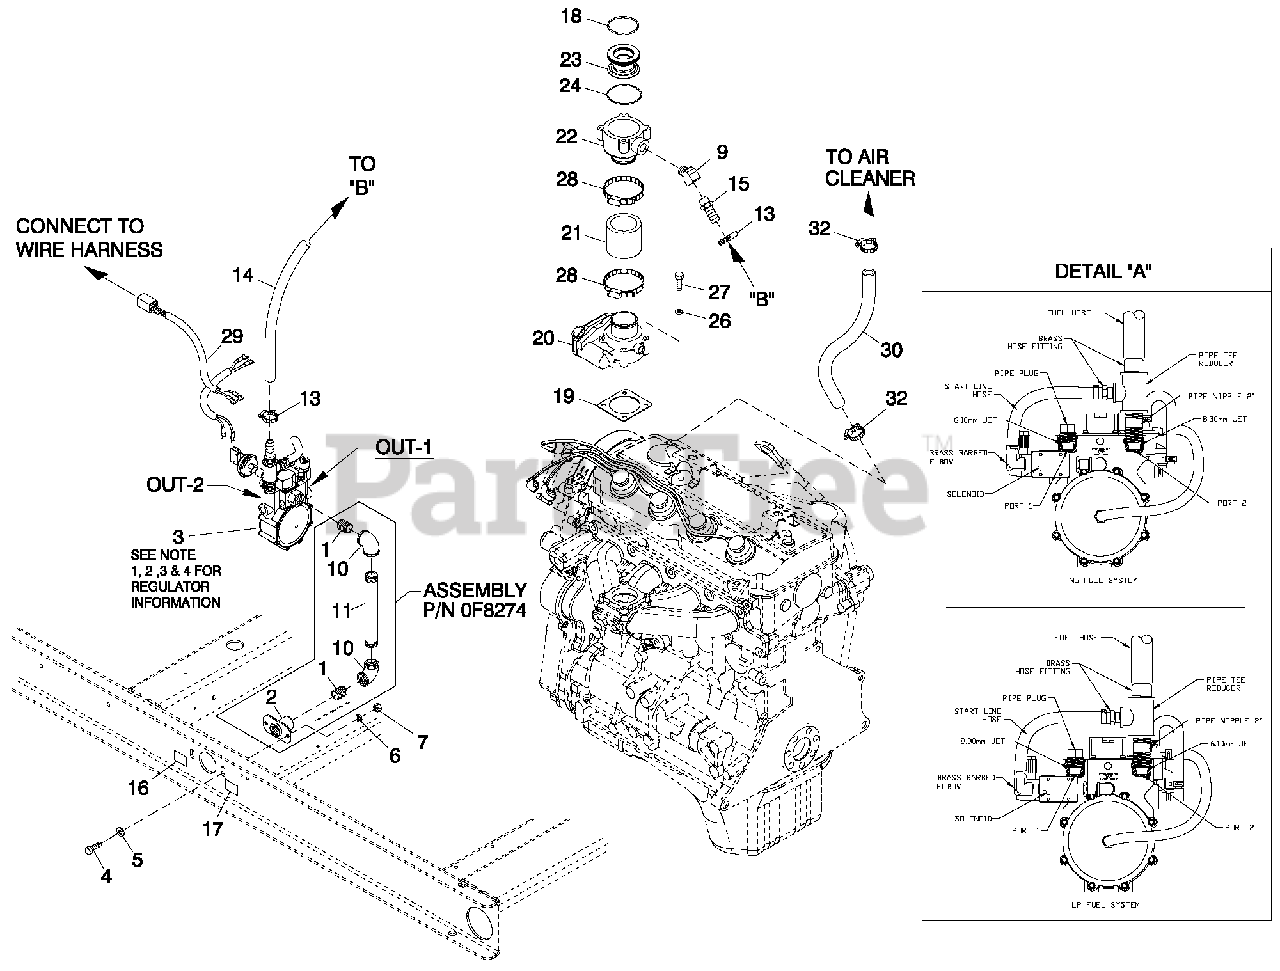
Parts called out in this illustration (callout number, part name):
1	NIPPLE CLOSE 3/4X1.375
2	FLANGE FUEL INLET
3	REGULATOR ASSY 2.4L (25KW)
4	SCREW HHC M8-1.25X 20 G8.8
5	WASHER FLAT 5/16-M8 ZINC
6	WASHER LOCK M8-5/16
7	NUT HEX M8-1.25 G8 CLEAR ZINC
9	STREET EL 45D1/2 NPT BRASS
10	ELBOW 90D 3/4 NPT
11	NIPPLE PIPE 3/4lNPTlX7
13	CLAMP HOSE #10.56-1.06
14	HOSE 3/4 ID LPG & NG (18" LG)
15	BARBED STR 1/2 NPT X 3/4
16	DECALlINLETlPRESSUREl
17	DECALlFUELlNLETlNGl(NATURALlGASlAPPLICATION)
18	O-RINGl45.63 DlX2.62 WIDTH
19	GASKET BOSCH 32
20	ACTUATOR BOSCH 40 GOVERNOR (45KW)
21	HOSE COOL 2 IN ID 20R4 (45KW)
22	MIXERACTUATOR 32MM MACHINED (25KW)
23	VENTURI THROTTLE 26MM (35&45K)
24	O-RING 47.625 IDlXl2.38 WIDTH
26	WASHER LOCK M6-1/4
27	SCREW SHC M6-1.0X45 G12.9
28	CLAMP HOSE#281.32-2.25
29	HARNESS CPL FUEL JUMPER
30	HOSE 3/8 ID SINGLE BRAID (18" LG)
32	CLAMP HOSE#10.56-1.06
